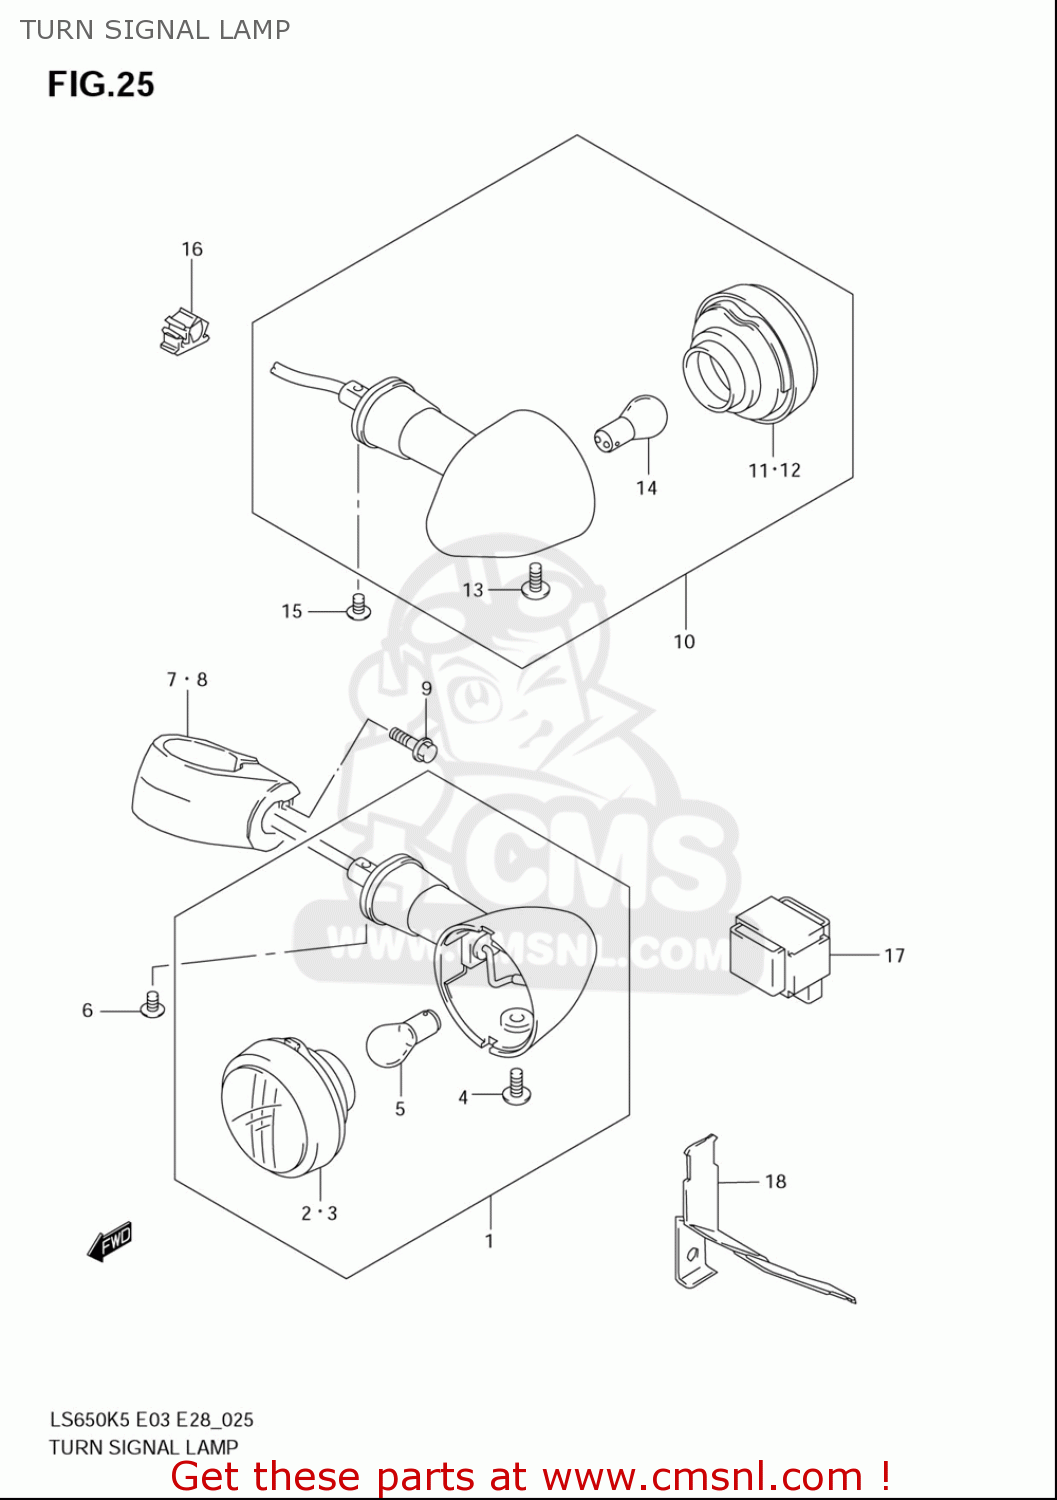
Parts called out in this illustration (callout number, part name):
1	LAMP ASSY,FR TURN SIGNAL,R
2	LENS
3	LENS
4	SCREW(4X10)
5	BULB(12V21/5W,BF141-49642A)
6	SCREW
7	BRACKET,FR TURNSIGNAL LAMP,R
8	BRACKET,FR TURNSIGNAL LAMP,L
9	BOLT
10	LAMP ASSY,RR TURNSIGNAL,R
11	LENS
12	LENS
13	SCREW(4X10)
14	BULB(12V21W)
15	SCREW
16	CLAMP
17	RELAY ASSY
18	BRACKET,TURNSIGNAL RELAY
